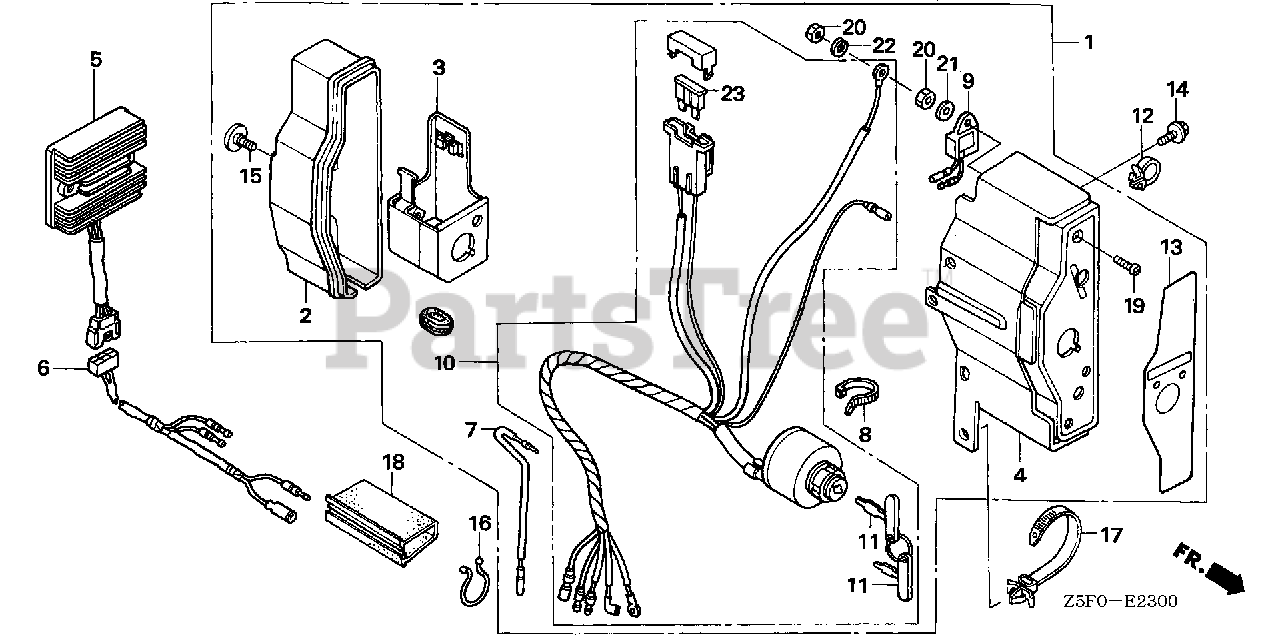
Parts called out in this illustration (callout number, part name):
1	BOX ASSY., CONTROL (18A) *R280* (EXP-ALERT) (POWER RED)
1	BOX ASSY., CONTROL (EXP-ALERT/18A) *NH1* (BLACK)
1	BOX ASSY., CONTROL (EXP-ALERT/18A) *R280* (POWER RED)
2	CASE, CONTROL
3	BRACKET, CASE MOUNTING
4	PANEL, CONTROL *R280* (POWER RED)
5	RECTIFIER ASSY., REGULATOR (20A)
6	SUB-WIRE HARNESS ASSY.
7	SUB-WIRE HARNESS
8	BAND
9	ALERT UNIT, OIL
10	SWITCH ASSY., COMBINATION (18A-CHARGE)
11	KEY
12	HOLDER, STOP SWITCH WIRE Use up to Engine SN 2056819.
13	MARK, CONTROL BOX (EXTERNAL-REGULATOR)
13	MARK, CONTROL BOX (EXP)
14	BOLT, FLANGE (6X12) (CT200)
15	SCREW, SPECIAL (6X12)
16	CLIP, PURSE LOCK
17	STRAP, CABLE (118MM) *NH1L* (Honda Code 1170653). (BLACK)
18	TUBE, FASTENER (30)
19	SCREW, PAN (4X12)
20	NUT, HEX. (4MM)
21	WASHER, PLAIN (4MM)
22	WASHER, SPRING (4MM)
23	FUSE, BLADE (25A)
